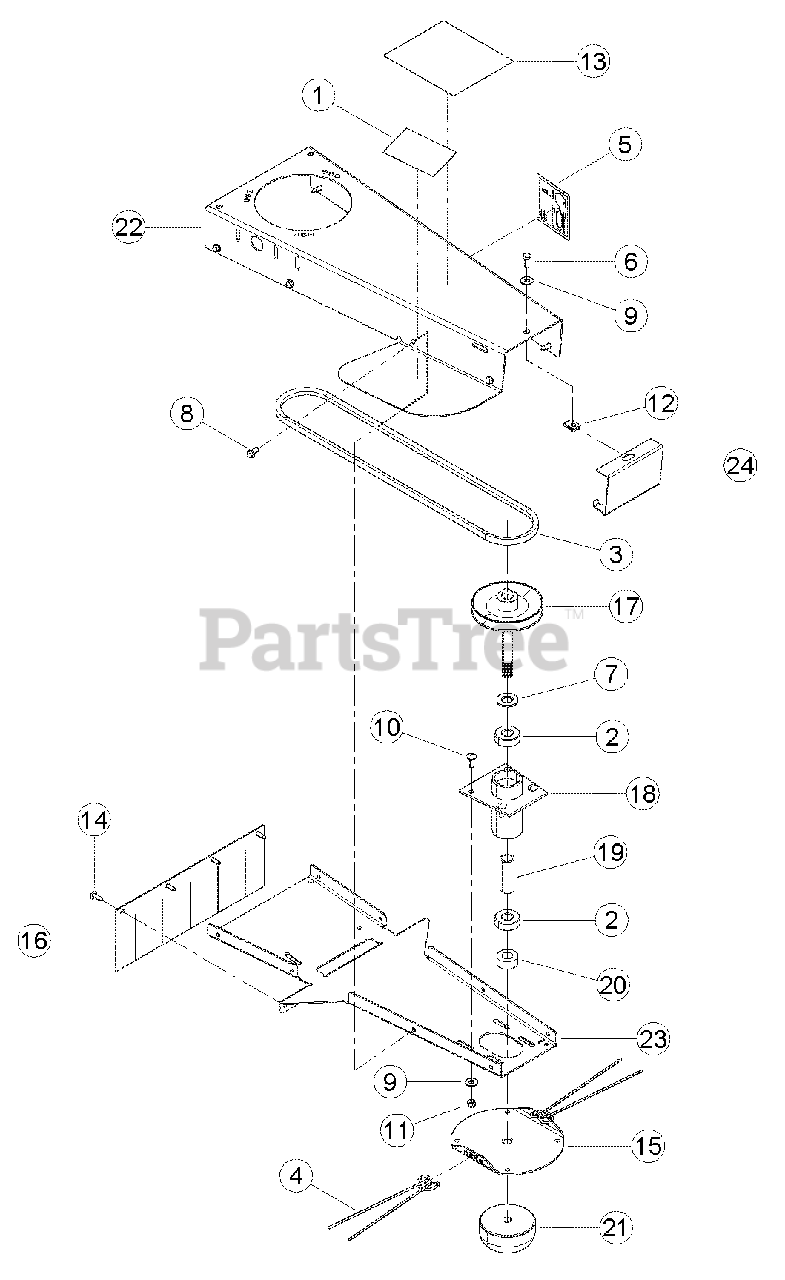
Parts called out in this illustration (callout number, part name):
1	DECAL, GRINDER DANGER
2	BEARING, 3/4 BALL
3	BELT, 4L 53 ARAMID
4	STRING, .155 X 20-1/2
5	DECAL, 101 DB
6	BOLT, 5/16 X 3/4 HEX HD GR5 ZP
7	WASHER, 3/4 SAE FLAT ZP
8	SCREW, 11/32 X 7/8 HWH AB THREAD ZP
9	WASHER, 5/16 FLAT ZP
10	BOLT, 5/16 X 7/8 CRG GR5 NC ZP
11	NUT, 5/16 NE NYLOCK ZP
12	NUT, 5/16-18 TINNERMAN U-TYPE
13	DECAL, MANUAL/SAFETY INFO
14	RIVET, PLASTIC 1/4 X 7/8
15	DISK, TRIMMER HEAD
16	FLAP, TRIMMER
17	WELDMENT, TRIMMER PULLEY
18	WELDMENT, SPINDLE HUB
19	SPACER, TRIMMER SPINDLE
20	SPACER, TRIMMER HEAD
21	WELDMENT, TRIMMER HEAD USE 72704-12
22	BODY, TRIMMER
23	BOTTOM, TRIMMER FRAME
24	COVER, FRONT TRIMMER
